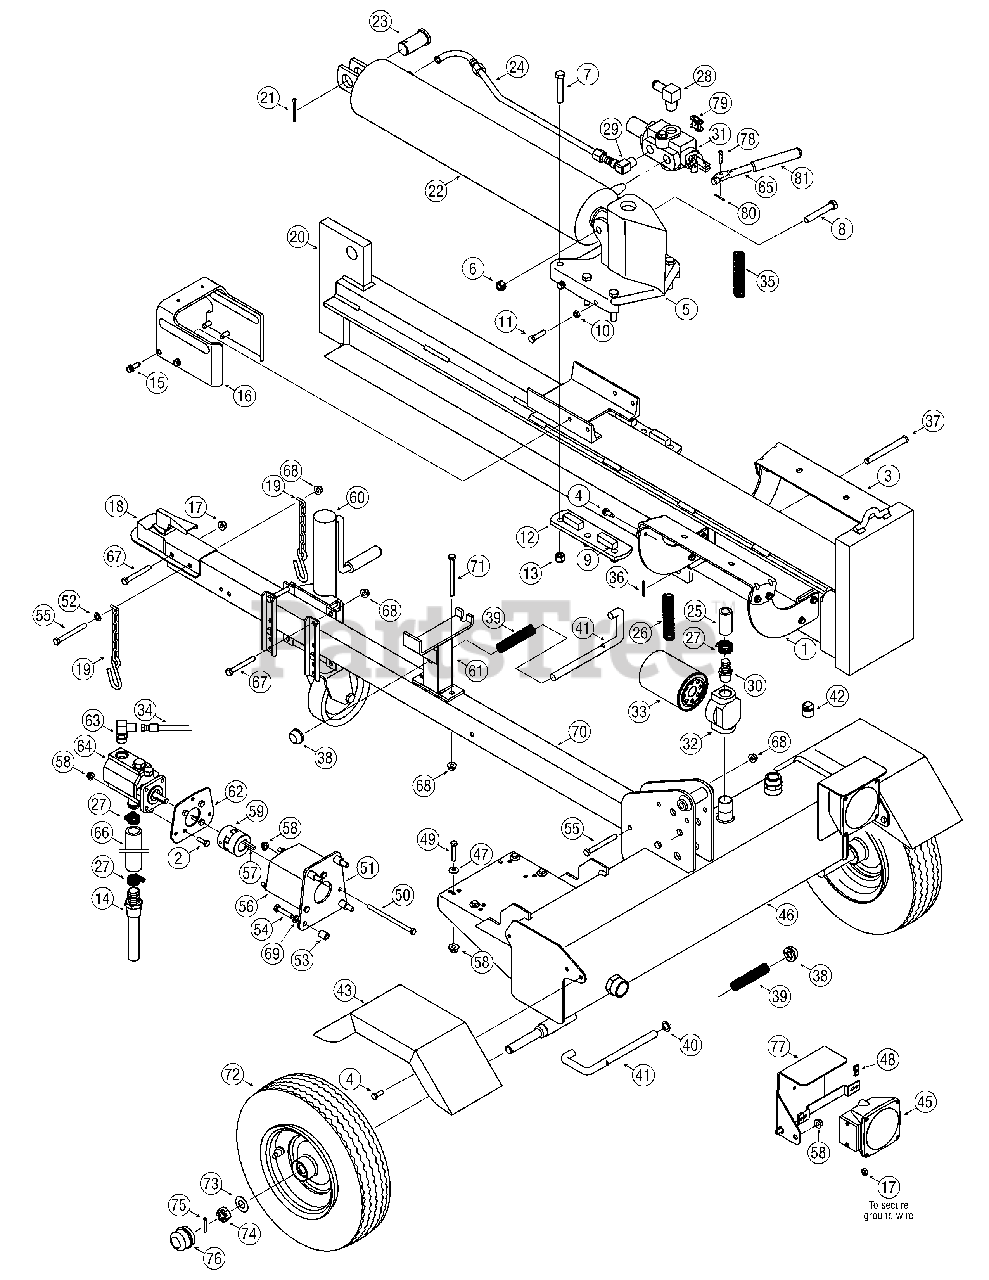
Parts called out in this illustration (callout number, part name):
2	Hex Screw, 5/16-18 x 1.00
4	TT Screw, 5/16-18 x .875
5	Wedge Assembly
6	Lock Nut 1/2-13
7	Hex Cap Screw 1/2-20 x 2.75
8	Hex Cap Screw 1/2-13 x 3.25
9	Adjustable Gib
10	Hex Jam Nut 3/8-24
11	Hex Cap Screw 3/8-24 x 1.5
13	Hex Lock Nut, 1/2-20
14	Inlet Filter
15	Hex Washer Screw 3/8-16 x 1.0
17	Jam Nut, 3/8-16
18	Hitch Coupler, 2-inch
20	Beam Assembly
21	Cotter Pin
22	Kit Seal 5.0" for Best Metals cylinder 718-0313
22	Hydraulic Cylinder
22	Kit Seal 5.0" for XINGHUI cylinder 718-0313A
22	Kit Seal 5.0" for ENERGY cylinder 718-0313A
23	Clevis Pin
24	Hydraulic Tube
25	Return Hose 3/4" ID x 44"
26	Hose Guard
27	Hose Clamp 5/8"
28	Return Elbow
29	90 Degree Solid Male Adapter
30	3/4" Hose Adapter
31	Control Valve
32	Filter Housing
33	Oil Filter
34	High Pressure Hydraulic Hose
35	Hose Guard
36	Cotter Pin 1/8"
37	Hinge Pin 1/2 x 4.8" Lg.
39	Compression Spring 4"
40	Flat Washer .635 ID x .93 OD
41	Locking Rod
42	Vented Dipstick
45	Tail Light Assembly
46	Frame Assembly 7.0 Gal
47	Bell Washer, 340 x .872 x .060
48	Nut 1/4-20
49	Hex Cap Screw 5/16-18 x 1.75
50	Hex Cap Screw 5/16-18 x 5.50
53	Spacer, .385 x .623 x .750
54	Hex Cap Screw 3/8-16 x 1.75
55	Hex Cap Screw 3/8-16 x 3.50
56	Coupling Shield
57	Key
58	Hex Flange Lock Nut, 5/16-18
59	Flex Coupling
60	Adjustable Jack Stand
63	Adapter 7/8-14
64	Pump
65	Hydraulic Valve Control
66	Suction Hose
67	Hex Cap Screw 3/8-16 x 3.0
68	Flange Lock Nut, 3/8-16
69	Lock Washer 3/8
71	Hex Cap Screw 3/8-16 x 4.0
72	Wheel Assembly
73	Flat Washer .76" ID x 1.5" OD
74	Slotted Nut 3/4-16
75	Cotter Pin 5/32" x 1-1/4"
79	Valve Handle Link
80	Cotter Pin
